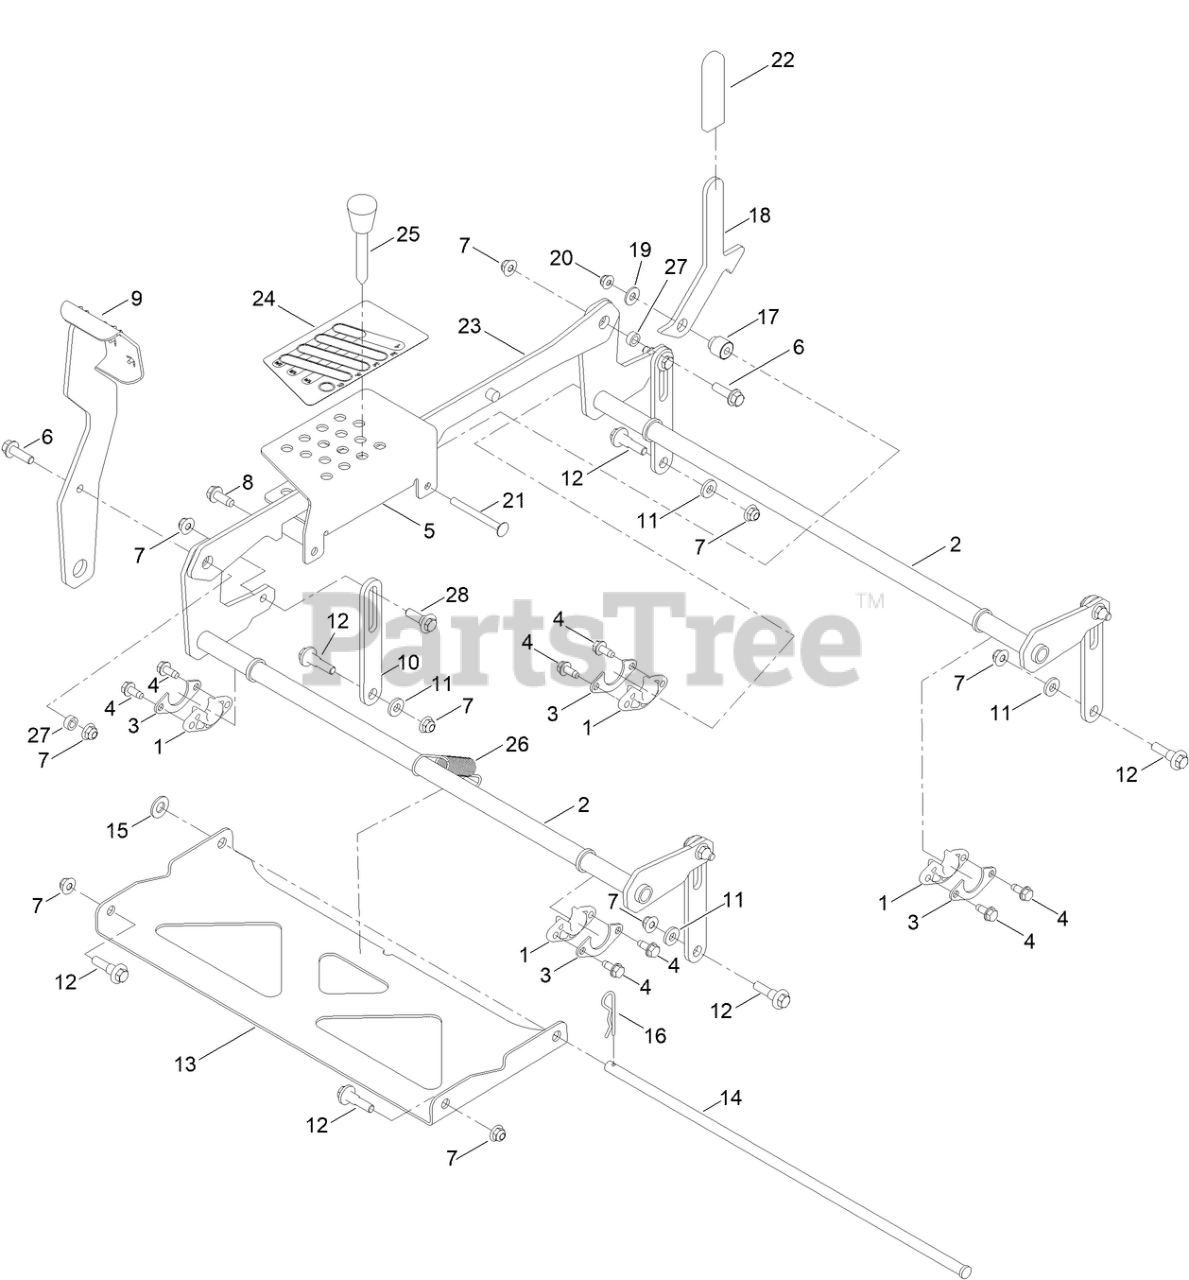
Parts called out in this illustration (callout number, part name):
1	BEARING-FLANGE
2	PIVOT ASM-DECKLIFT [RED]
3	GUSSET-DECK LIFT
4	SCREW-HWHTF
5	BRACKET-HOC
6	SCREW-HHF
7	NUT-HF, NI
8	SCREW-HWH
9	PEDAL ASM [RED]
10	LINK-HOC
11	SPACER-HUB, BLOWER
12	BOLT-SHOULDER
13	PAN-DECK PIVOT
14	PIN-DECK
15	WASHER-FLAT
16	PIN-HAIR
17	SPACER-STEPPED
18	PLATE-TRANSPORT LOCK
19	WASHER-PLAIN
20	NUT-HF
21	SCREW-CARR
22	GRIP-HANDLE
23	LINK ASM-HOC [RED]
24	DECAL-HOC, TITAN
25	HOC PIN ASM
26	SPRING-EXTENSION
27	SPACER
28	SCREW-SHOULDER, HWH
